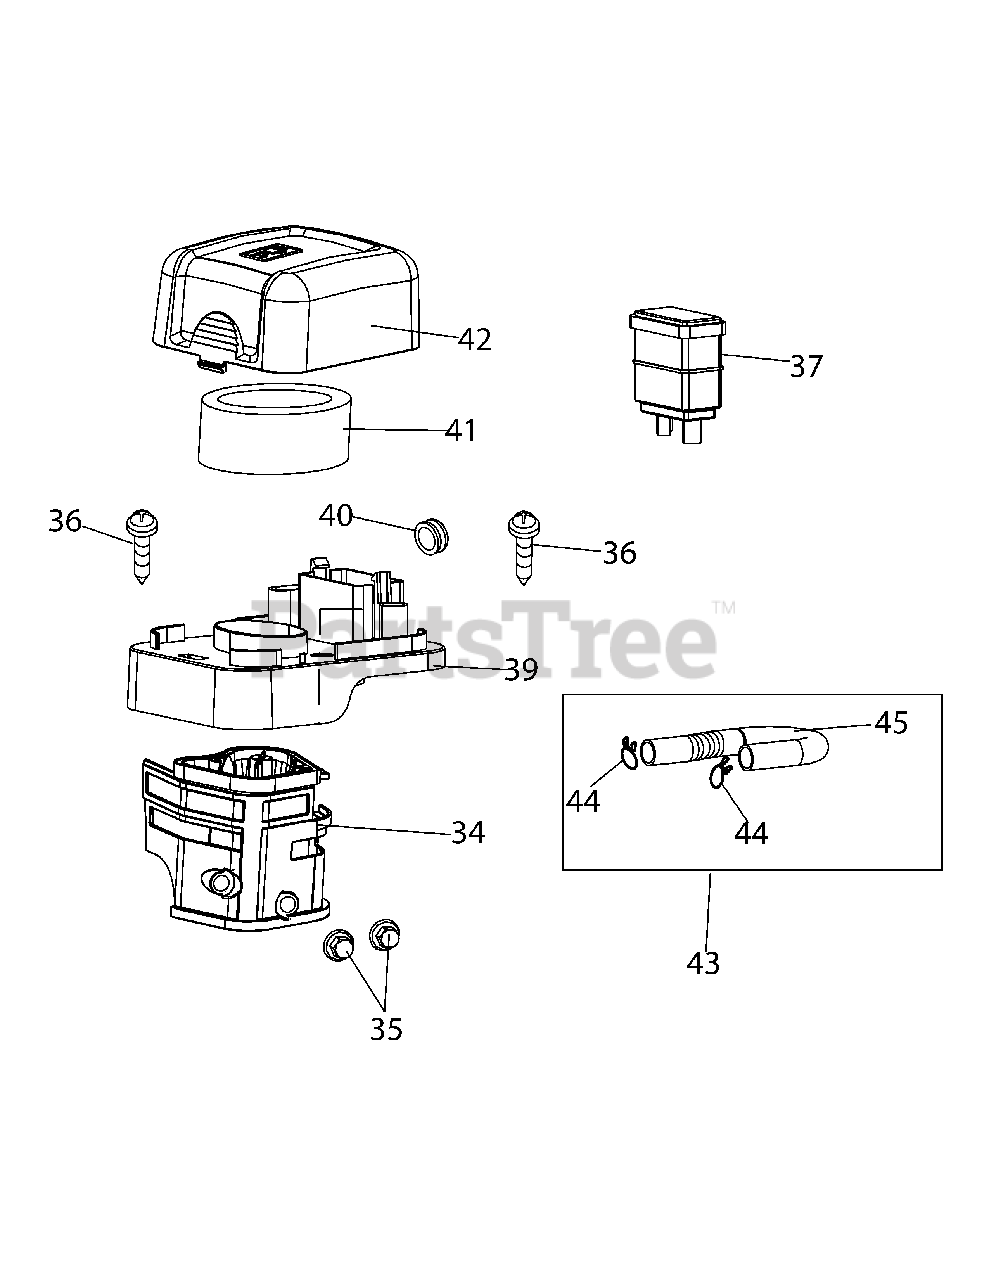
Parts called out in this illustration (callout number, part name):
34	Air Cleaner Housing
36	Self-Tapping Bolt M4.2×16
37	Carbon Canister
39	Silencer Plate
40	Rubber Shock Pad
41	Air Filter Assembly
42	Air Filter Cover
43	Primer Hose
45	Exhaust Piping
